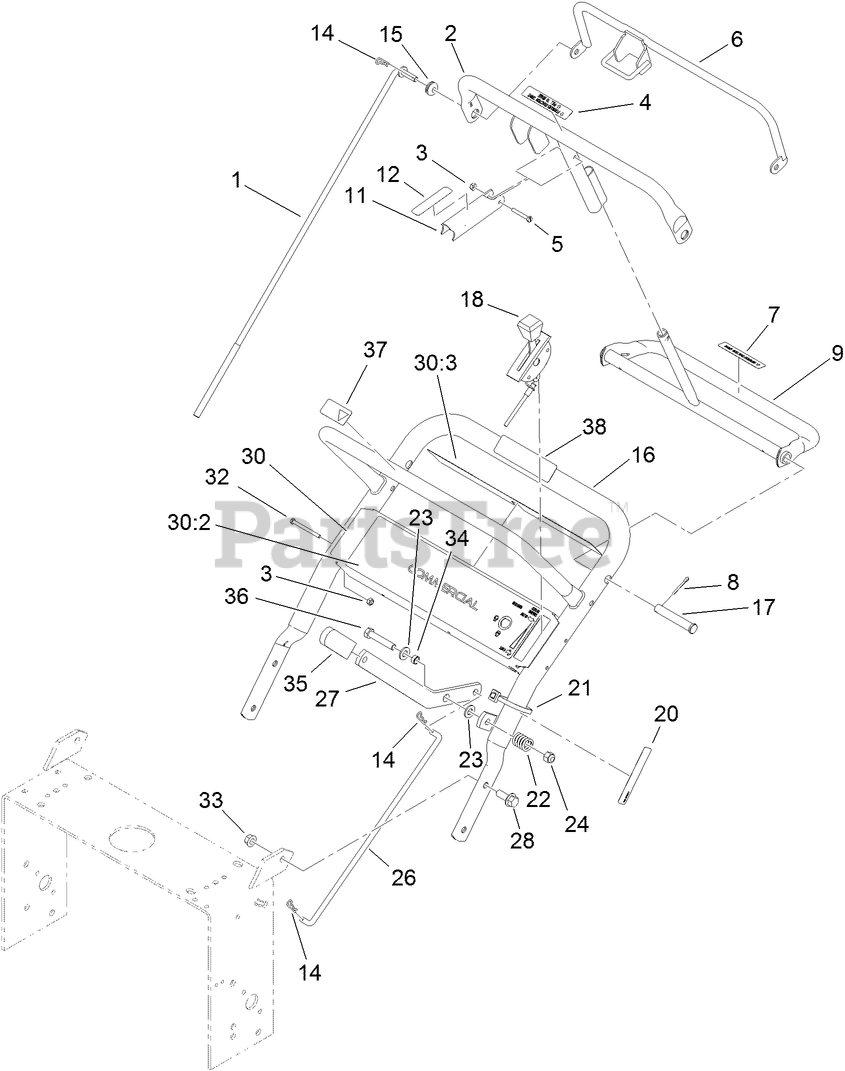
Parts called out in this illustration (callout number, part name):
1	ROD-CONTROL
2	BAR-CONTROL
3	NUT-LOCK, NI
4	DECAL-BAR, CONTROL
5	SCREW-SHH
7	DECAL-REVERSE
8	PIN-COTTER
9	PIVOT-CONTROL
11	LEVER-BRAKE, PARKING
12	DECAL-LEVER, PARKING
14	PIN-COTTER
15	GROMMET-RUBBER
16	HANDLE-UPPER
17	PIN-CLEVIS
18	CABLE-THROTTLE
20	DECAL-ENGAGE, DECK
21	TIE-PLASTIC
22	SPRING-COMPRESSION
23	WASHER-FLAT
24	NUT-HF, NI
26	LINKAGE-DRIVE, BLADE
27	LEVER-ENGAGEMENT, BLADE
28	SCREW-HHF
30	CONTROL PANEL ASM
30:2	DECAL-PANEL, CONTROL
30:3	DECAL-DANGER
32	SCREW-SHH
33	NUT-HF
34	SPACER
35	GRIP-LEVER
36	SCREW-HH
37	DECAL-PROTECTION, EAR
38	DECAL-ARRESTER, SPARK
